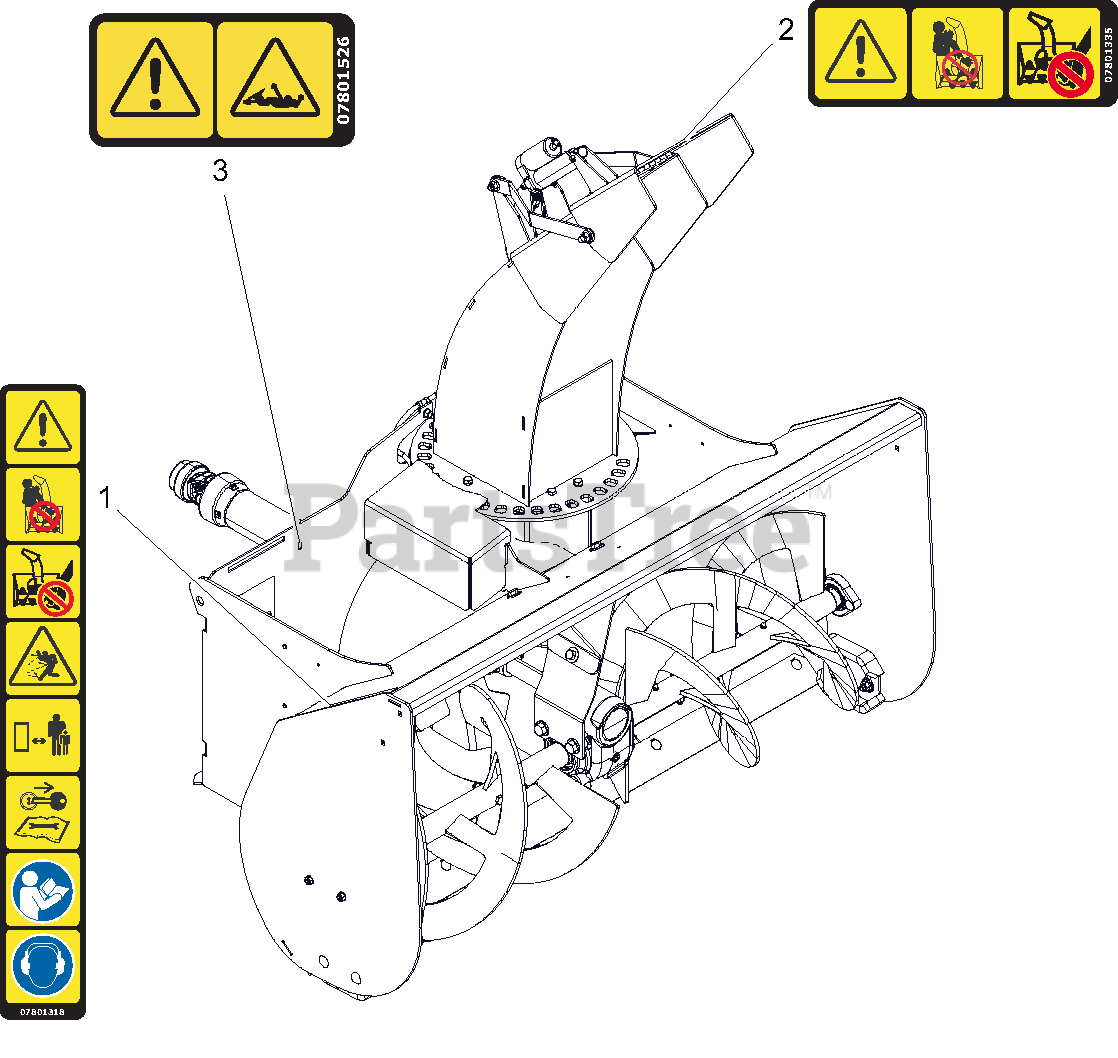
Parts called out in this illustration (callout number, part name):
1	DECAL- SAFETY - DANGER
2	DECAL- DANGER
3	DECAL- SAFETY - ROTATING SHAFT
